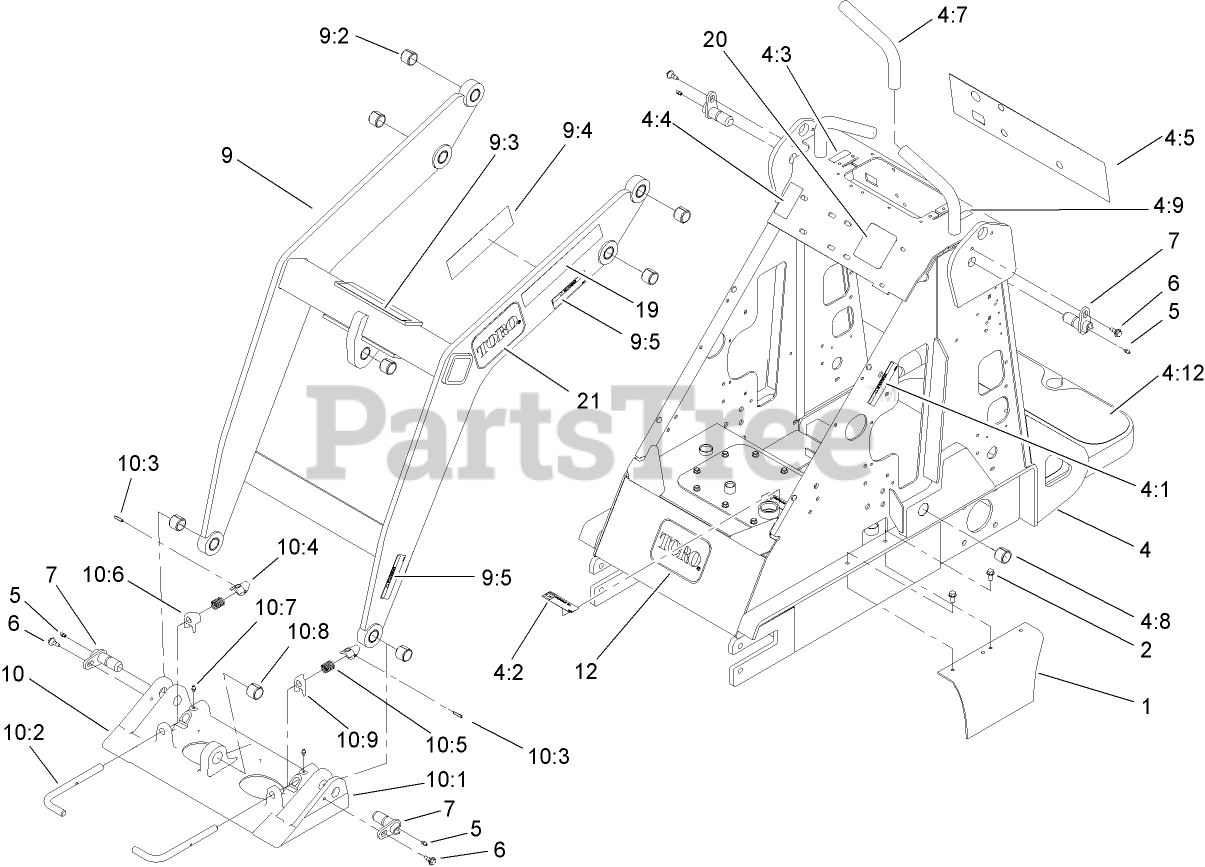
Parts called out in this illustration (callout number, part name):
1	COVER-CHAIN
2	SCREW-HWHTF
4	FRAME ASM
4:1	DECAL-PINCH
4:2	DECAL-OIL, HYD
4:3	DECAL-CHOKE
4:4	DECAL-POWER, AUXILIARY
4:5	DECAL-PANEL, CONTROL
4:7	GRIP-CUSHION
4:8	BUSHING-TENSION
4:9	DECAL-THROTTLE
4:12	TREAD-FOOT
5	FITTING-GREASE
6	BOLT-SHOULDER
7	PIN-PIVOT
9	LOADER ASM
9:2	BUSHING-TENSION
9:3	DECAL-CAUTION
9:4	DECAL-DANGER
9:5	DECAL-PINCH
10	QUICK ATTACH ASM
10:1	MOUNT-ATTACH, QUICK
10:2	PIN-LOCKING
10:3	PIN-GROOVED
10:5	SPRING-COMPRESSION
10:6	STOP-RH
10:7	FITTING-GREASE
10:8	BUSHING-TENSION
10:9	STOP-LH
12	DECAL
20	DECAL-SELECTOR, SPEED
21	DECAL
